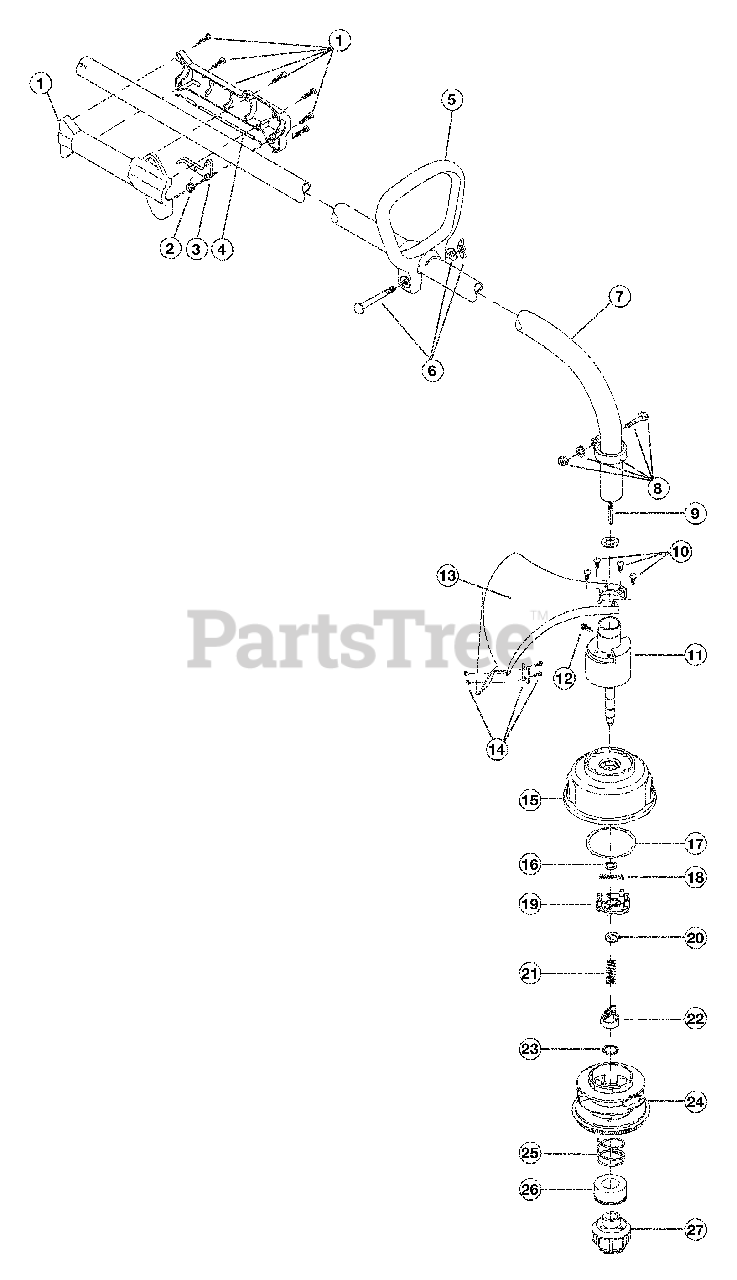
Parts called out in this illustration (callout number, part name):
1	Throttle Housing Assembly
2	Throttle Trigger Spring
3	Throttle Trigger
4	Throttle Cable Assembly
5	D-Handle Assembly
6	D-Handle Hardware
7	Drive Shaft Housing Assembly
8	Lower Clamp Assembly
9	Flexible Drive Shaft
10	Shield Mounting Screw
11	Bushing Housing Assembly
12	Anti-Rotation Screw
13	Shield Assembly
14	Blade Assembly
15	Outer Spool Assembly
16	Retainer
17	Thrust Washer
18	Small Spring
19	Slider
22	Plunger
24	Inner Reel
25	Large Spring
26	Foam Seal
27	Bump Head Knob Assembly
